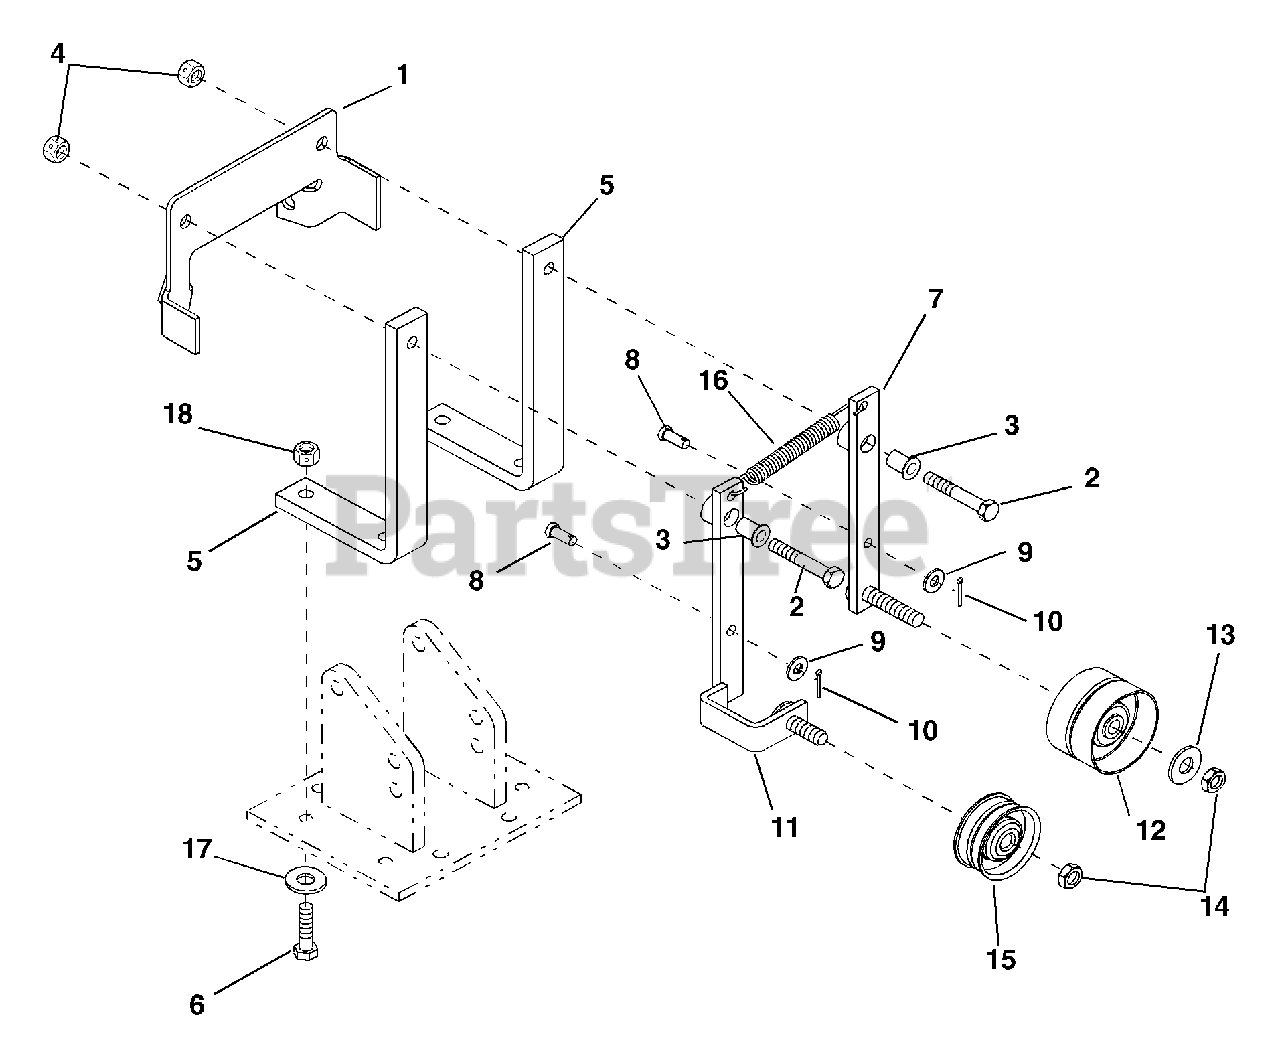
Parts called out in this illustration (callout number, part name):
1	PLATE, ANCHOR
2	@BLT-HEX .31-18X2.00 GR5 YWZC
3	BSHG-FLG .325X.465X.831X.685
4	@NUT-LK-CTR .31-18 YWZC
5	SHIFT MOUNTING BAR
6	@BLT-HEX .38-16X1.50 GR5 YWZC
7	IDLER ARM - FORWARD
8	PIN-CLEV .25X.62
9	@WSHR-FL-STL.281X.62X.065 YWZC
10	@PIN-CTR .06X.50 EXTPRSQCT YWZ
11	IDLER ARM - REVERSE
12	IDLER-FLAT 2.25 X .38
13	@WSHR-FL-STL.438X1.00X.083 YWZ
14	@NUT-LK-CTR-JAM .375-16 YWZC
15	IDLER-FLAT 2.000X.375
16	SG-TENS .047X.44X3.5 WLD 3
17	@WSHR-FL-STL.406X.812X.065 YWZ
18	@NUT-LK-CTR .38-16 YWZC
